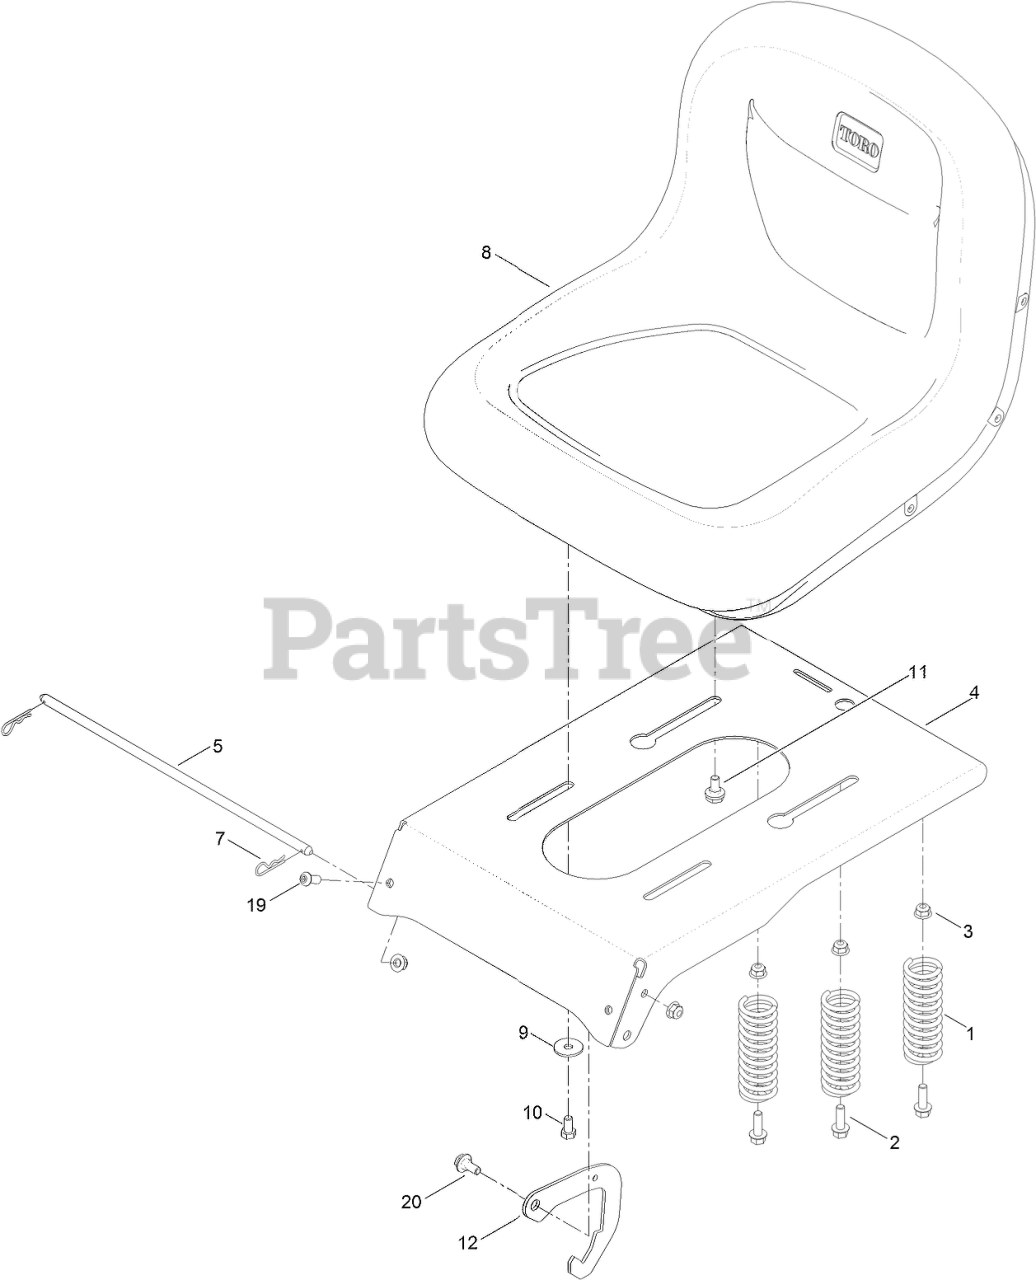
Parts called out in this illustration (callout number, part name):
1	SPRING-COMPRESSION
2	SCREW-HHF
3	NUT-HF, NI
4	PAN-SEAT
5	ROD-PIVOT, NARROW
7	PIN-COTTER
8	SEAT-18 INCH
9	WASHER-PIVOT
10	SCREW-HH
11	BOLT-SHOULDER,HFH
12	LATCH-SEAT
19	SCREW-HSBH
20	SCREW-SHOULDER
